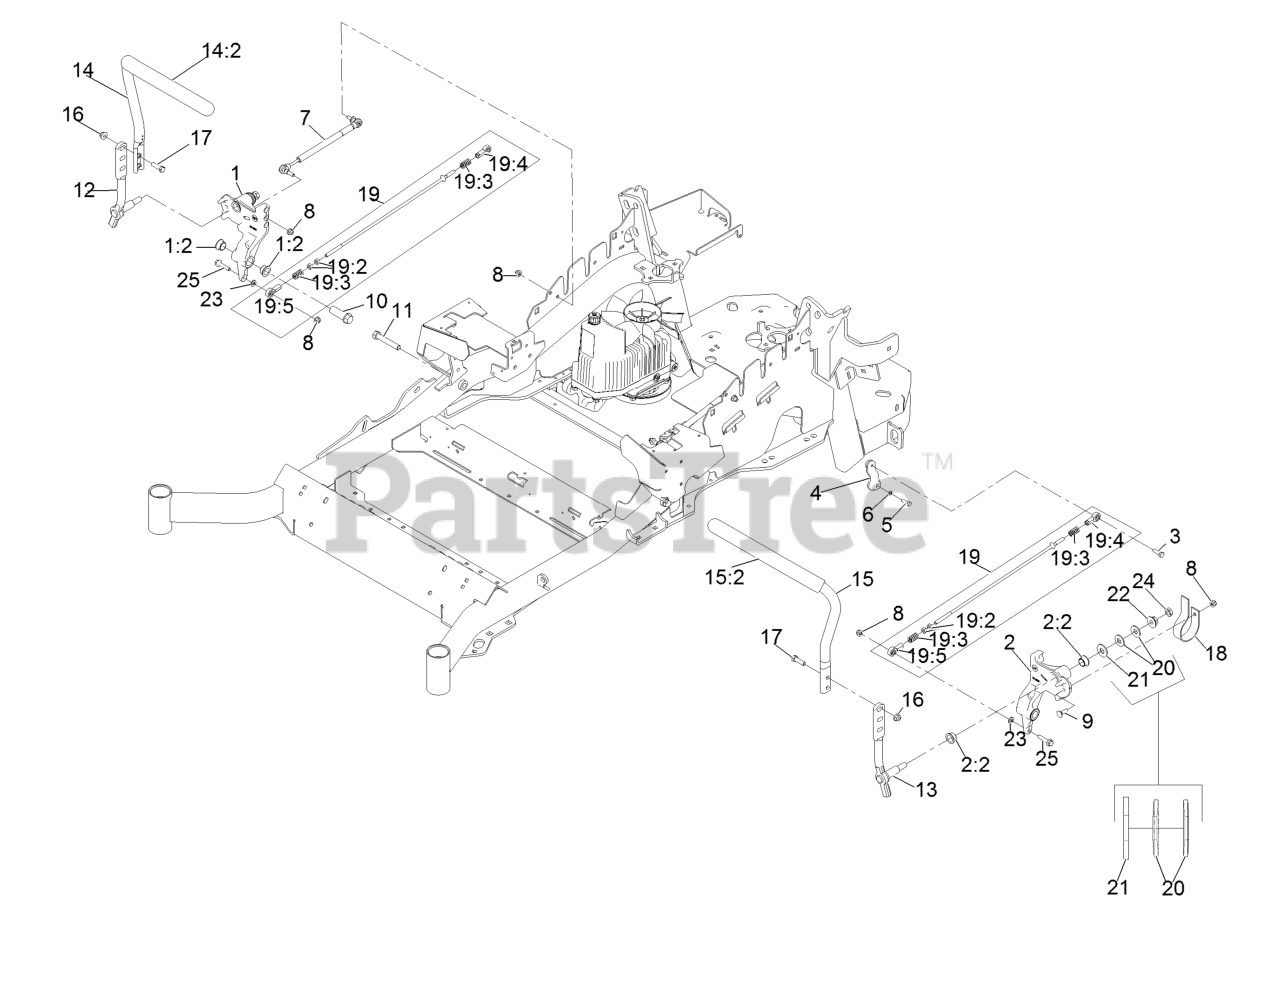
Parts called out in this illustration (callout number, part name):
1	RH Motion Control And Bushing ASM
1:2	Bushing-Flanged
2	LH Motion Control And Bushing ASM
2:2	Bushing-Flanged
3	Screw-HH 5/16-18 X 1 W/Patch
4	Arm-Control, Pump
5	Screw-HH 1/4-20 X 7/8
6	Washer-Spring Disc 1/4
7	Damper-Control, Motion
8	Nut-Nyloc 5/16-18 Flg
9	Bolt-Carriage 5/16-18 X 1
10	Hub-Threaded
11	Screw-HH 1/2-13 X 3
12	Lever-Control Motion, RH
13	Lever-Control Motion, LH
14	RH Steering Handle ASM
14:2	Grip-Control, Lever
15	LH Steering Handle ASM
15:2	Grip-Control, Lever
16	Nut-Nyloc 3/8-16 Flg
17	Screw-HH 3/8-16 X 1 1/4
18	Spring-Leaf
19	Pump Linkage Rear ASM
19:2	Nut-Hex 5/16-24
19:3	Spring-Compression
19:4	Balljoint
19:5	Balljoint
20	Washer, Spring Disc 1/2
21	Washer
22	Nut-Hex 1/2-13 Flange
23	Washer-5/16 SAE
24	Nut-Jam 1/2-13
25	Screw-Hex Flange 5/16-18 X 1 1/2
